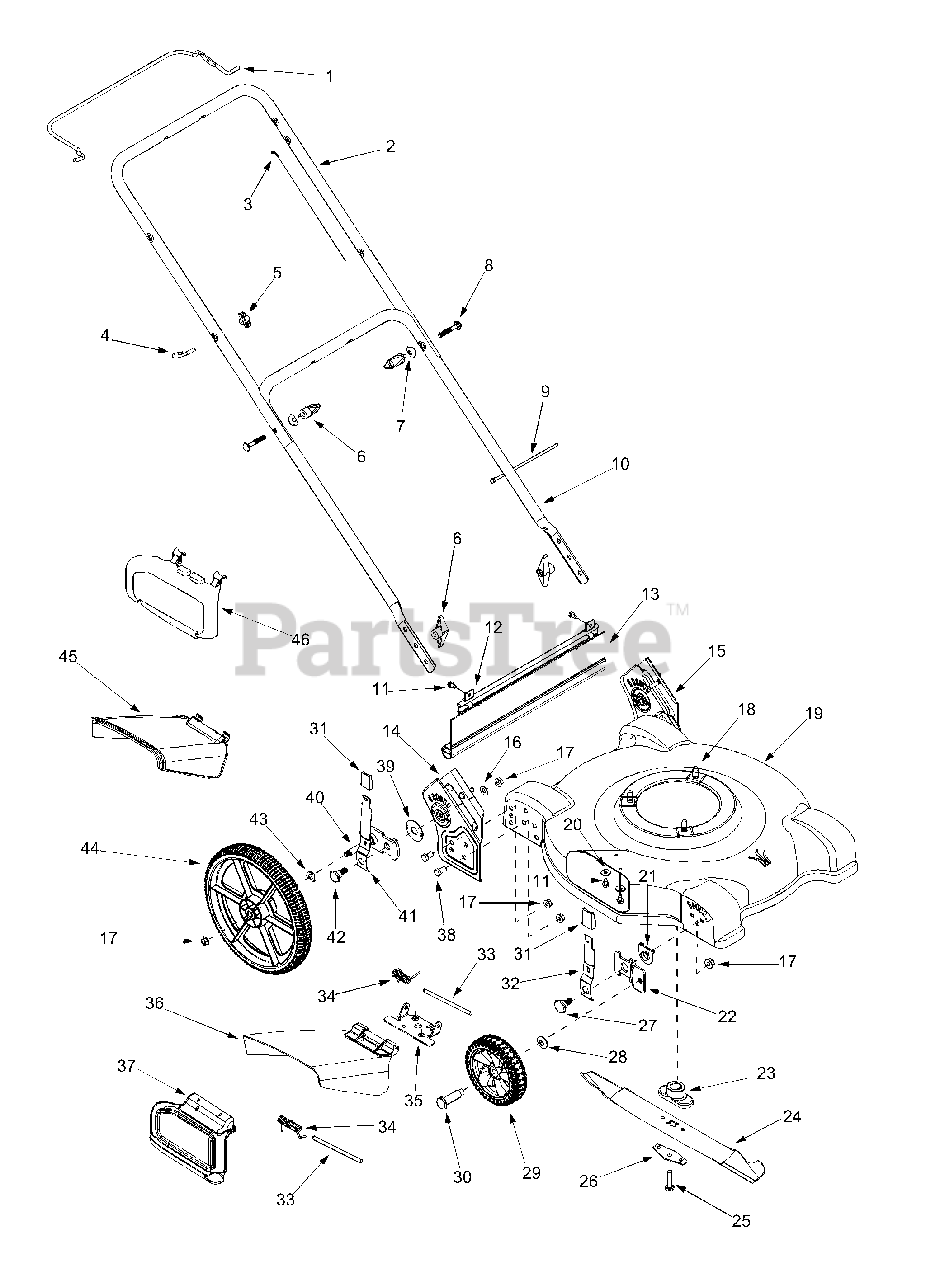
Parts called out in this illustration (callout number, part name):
1	Blade Control Handle
3	Control Cable - B&S
4	Eye Bolt
5	Wing Nut
6	Wing Nut
7	Shoulder Washer .320 ID x .93 OD
8	Carriage Bolt 5/16-18 x 2.0
9	Cable Tie
11	Hex Washer Screw 1/4-20 x .50
12	Hinge Clip
13	Trail Shield
17	Lock Nut 3/8 -16
18	Hex Washer Screw 3/8-16 x 1.0
20	Bell Washer .265 x .75
21	Height Adjuster Bearing
22	Pivot Arm Assembly
23	Blade Adapter
24	Blade 22"
25	Hex Cap Screw 3/8-24 x 1.5
26	Blade Bell Support
27	Shoulder Screw 3/8 - 16 x .302
28	Bell Washer .401 ID x .870 OD
29	Wheel Comp 7 x 1.8
30	Shoulder Screw 3/8 - 16
31	Height Adjuster Knob
32	Front Spring Lever
33	Hinge Pin
34	Torsion Spring - Side Discharge
35	Chute Hinge
36	Side Discharge Chute Assembly
37	Mulching Baffle
38	Hex Cap Screw 3/8-16 x .75
39	Thrust Bearing .688 ID x 1.938 OD
40	Rear Pivot Arm Assembly
41	Rear Spring Lever
42	Shoulder Screw 3/8 - 16 x .442
43	Spring Washer
44	Wheel Comp 14 x 1.8
45	Snap Discharge Chute
46	Snap Mulching Plug
